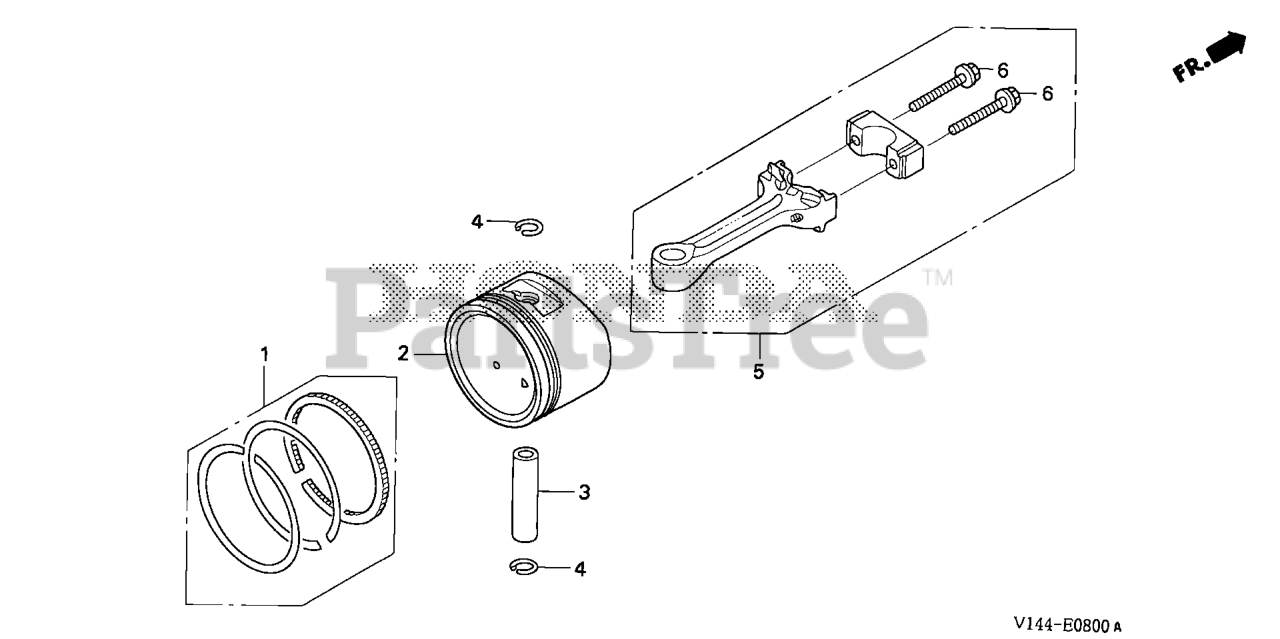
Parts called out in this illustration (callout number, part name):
1	RING SET, PISTON (STD)
2	PISTON (STD)
3	PIN, PISTON (10X33)
3	PIN, PISTON
4	CLIP, PISTON PIN (10MM)
5	ROD ASSY., CONNECTING
6	BOLT, CONNECTING ROD
